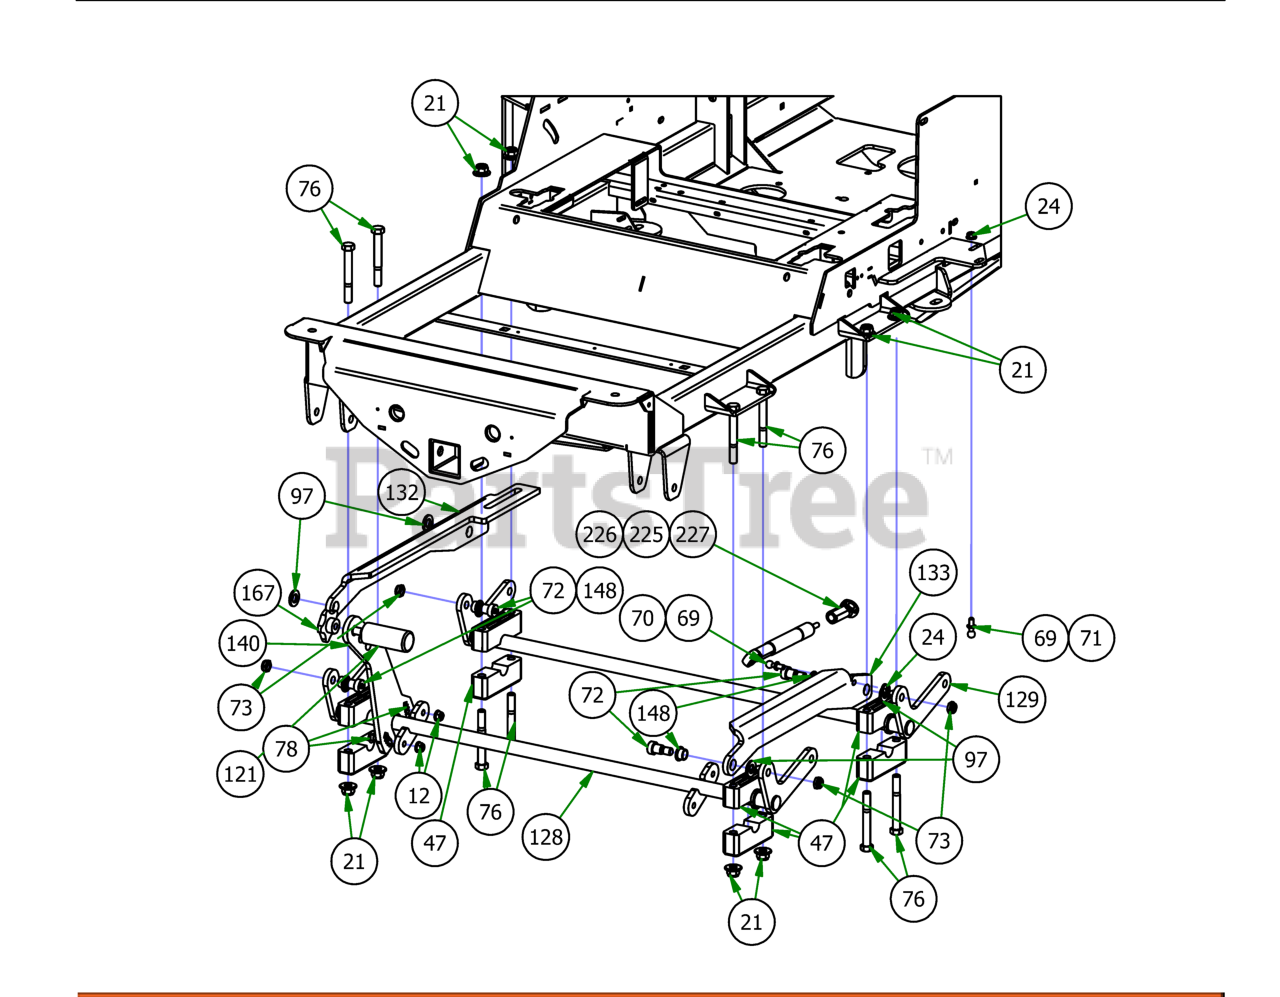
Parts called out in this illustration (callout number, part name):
12	3/8" Nylock Flange Nut
21	1/2-13 NYLON INSERT FLANGE LOCKNUT ZINC
24	5/16" Flange Nut
47	Pillow Block Assembly
69	13mm Damper Ball Stud-Steering
70	10mm Damper Ball Stud-Steering
71	10mm Damper Ball Stud-XP Linkage
72	5/8'' x 5/8'' Shoulder Bolt
73	1/2" Nylcock Nut (1/2 Jam)
76	1/2" x 4" Bolt (Grade 8)
78	3/8" x 1 1/4" Carriage Bolt
97	.630 ID Plastic Washer
121	Knurled Pedal
128	2019 Outlaw Actuator - Front
129	2019 Outlaw Actuator - Rear
132	2019 Actuator Linkage - Right
133	2019 Actuator Linkage - Left
140	Foot Lift Upright Lever
148	Bronze Bushing - SF - 2024-8
167	Foot Pedal Knob 1/2-13
206	2019 Veritical Suspension Frame
225	200 lb Gas Spring- 54" Deck outlaw
226	250lb Gas Spring - 61" Deck
227	300lb Gas Spring - 72" Deck
